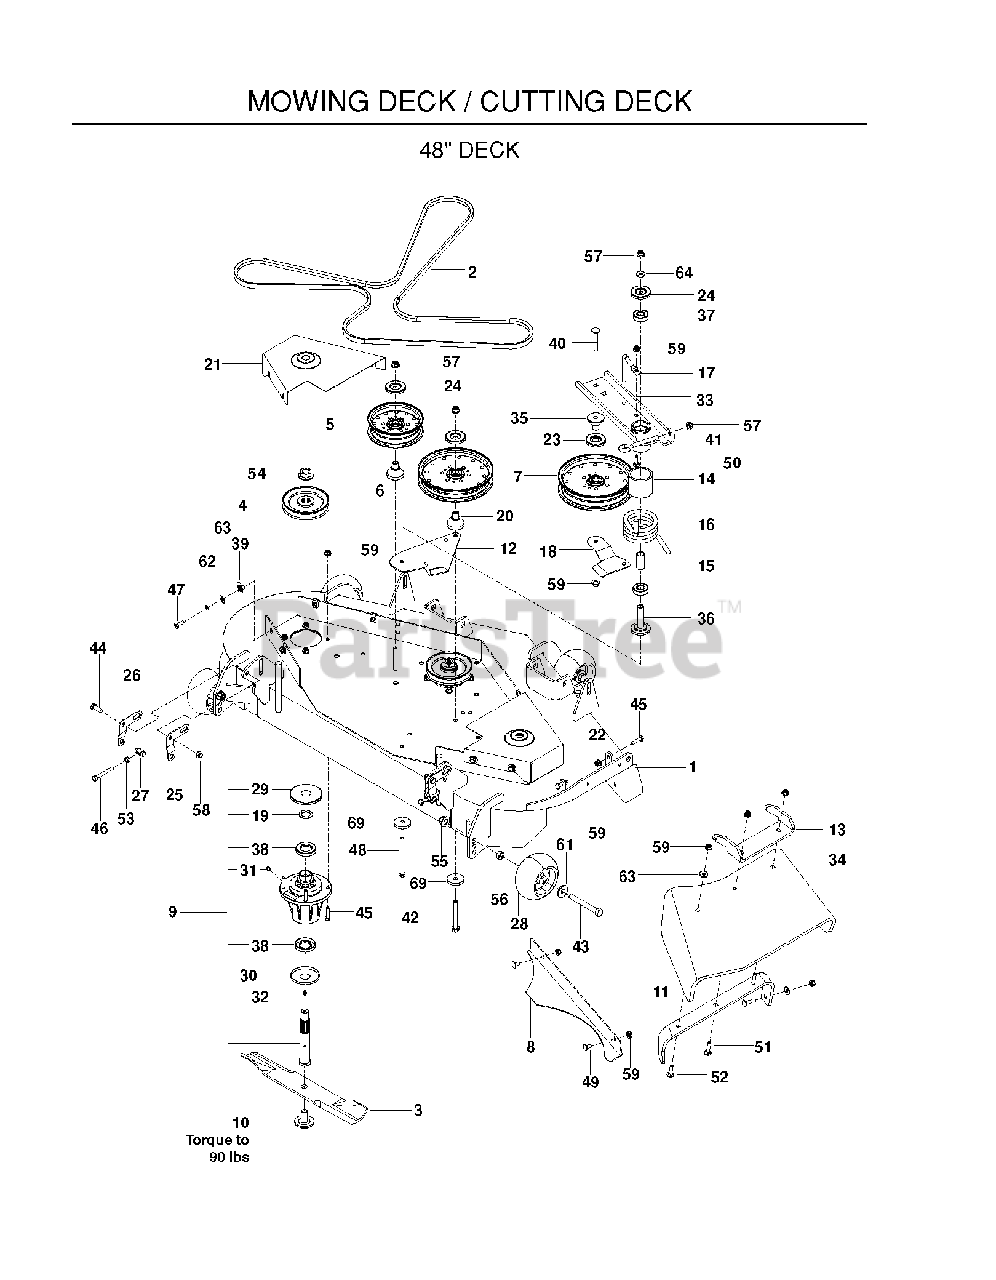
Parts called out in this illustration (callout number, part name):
4	PULLEY 42-48
5	IDLER PULLEY
6	PULLEY - 7" NARROW
7	PULLEY - IDLER 7"
8	CONFINEMENT PLATE 48" BLK
10	BLADE BOLT/WASHER
11	BRKT, REINF - CHUTE 52/61"
13	PIVOT BRACKET - CHUTE
14	SPACER, IDLER PIVOT
15	SPACER, IDLER BEARINGS
16	SPRING, TORSION, IDLER
17	BELT KEEPER
18	BELT GUIDE, BLK
19	MACHINE BUSHING
21	BELTSHIELD - L.H. BLUE
22	BELTSHIELD - R.H. BLUE
23	SHIELD, DUST
24	DUST SHIELD
25	PITCH, ADJUST, LT
26	PITCH, ADJUST, RT
27	TRUNION, PITCH
29	TOP DUST CAP
30	BOTTOM DUST CAP
31	PLUG-VENTED
35	BEARING, IDLER ARM
36	BEARING, IDLER PIVOT
37	BEARING, BALL
38	SHAFT SEAL
39	U-CLIP 5/16-18 NUT RETAINER
40	CARRIAGE BOLT 3/8-16 X
41	EYE BOLT, 3/8 X 4"
43	HCS 1/2-13 X 4 GR 5 ZD
44	HCS 3/8C X 1
45	HCS 5/16C X 1 1/4
46	HCS 5/16-18 X 2 1/2 TPBLT
47	HCS 5/16C X 3/4
48	HCS 3/8-16 X 4-1/2 GR 8 ZD
49	CARRIAGE BOLT 5/16C X 5/8"
50	RHSSNB 5/16C X 1.0
51	RHSNB 5/16-18 X 1-1/2 GR 5 ZD
52	BOLT, CARRIAGE 5/16X1-1/4
53	NUT 5/16C HEX
54	NUT FLANGE 3/4-16
55	NUT, 1/2-13 HEX FLG NYLOC ZD
56	NUT 1/2 HEX JAM
57	NUT 3/8-16 HEX FLG NYLOC ZD
58	NUT 3/8-16 NYLOC
59	5/16-18 NYLOC FLANGE NUT
60	SPINDLE WASHER
61	WASH USS FLAT 1/2
62	WASH 5/16 DISC SPRING ZD
63	WASHER 5/16 FLAT
64	WASHER, 3/8 THICK
